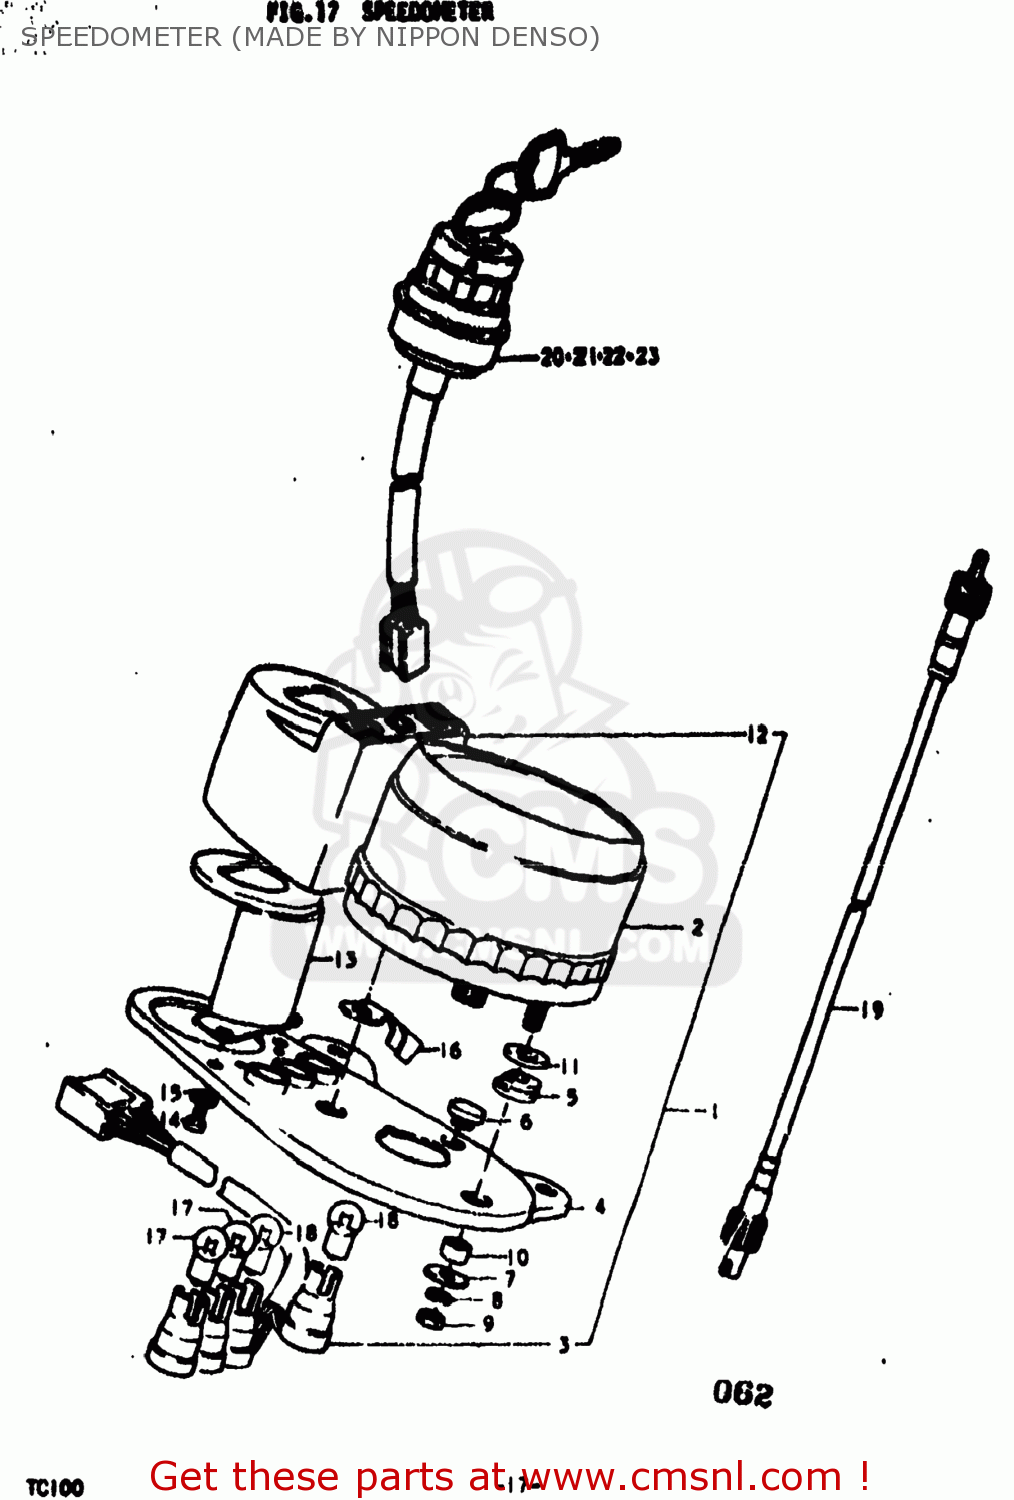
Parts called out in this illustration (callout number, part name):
1	SPEEDOMETER ASSEMBLY
2	SPEEDOMETER ASSEMBLY
3	SOCKET,METER
4	BRACKET,METER
5	CUSHION,TACHOMETER
6	CUSHION,METER
7	WASHER (5.5X16X1.2)
8	LOCK WASHER
9	NUT
10	SPACER,METER
11	WASHER,METER
13	ROTOR,SPEED
14	SCREW
15	LOCK WASHER
16	COVER,METER,UNDER
17	BULB(6V1.7W,STANLEY,A61A)
18	BULB(6V/3W)
19	CABLE ASSEMBLY,SPEEDOMETER
20	SWITCH ASSEMBLY,IGNITION
21	SWITCH ASSEMBLY,IGNITION
22	SWITCH ASSEMBLY,IGNITION
23	SWITCH ASSEMBLY,IGNITION
